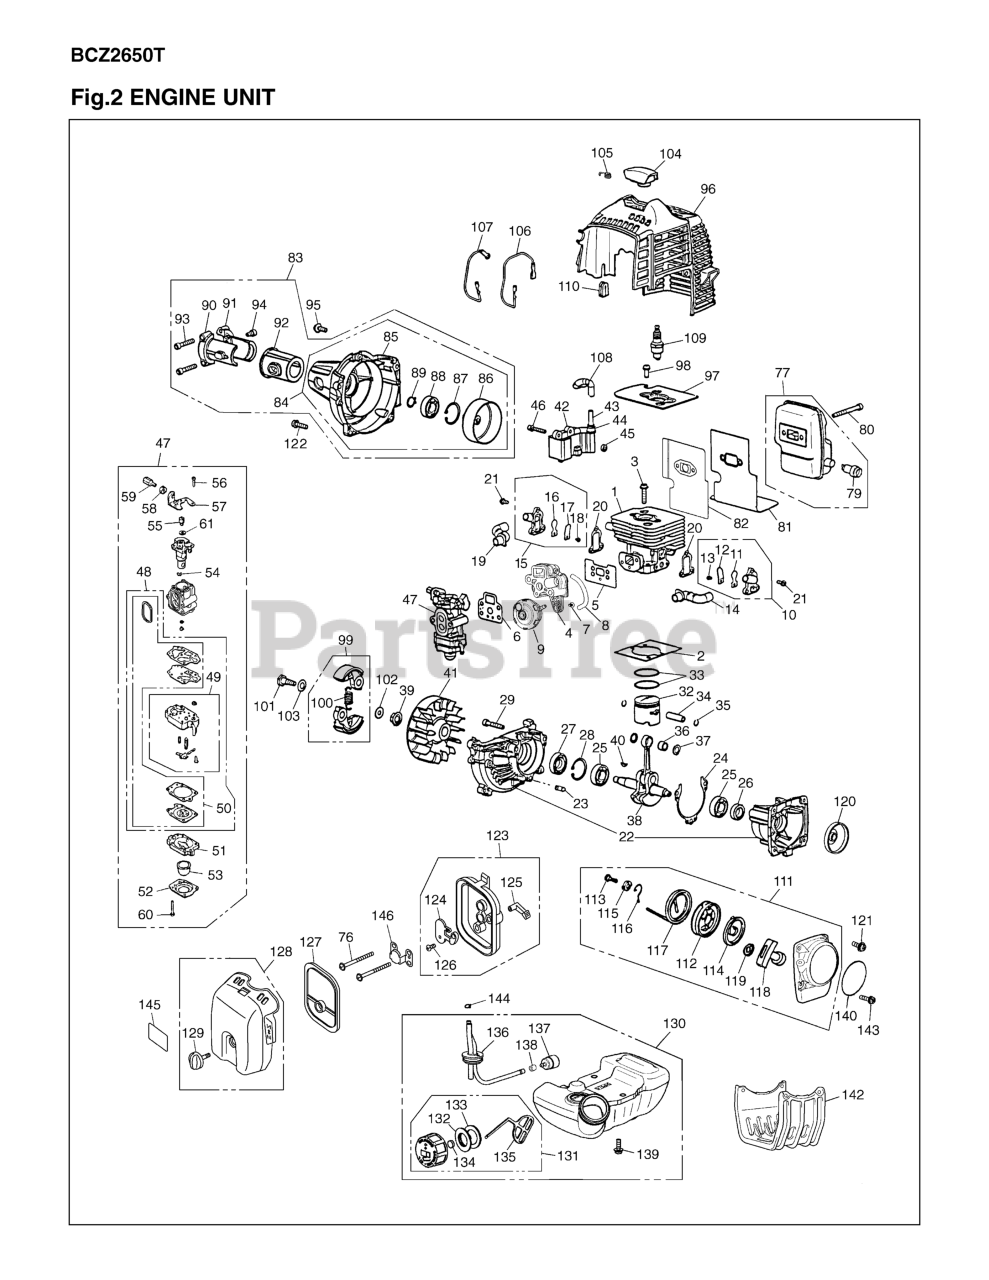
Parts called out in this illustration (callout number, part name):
1	CYLINDER
2	GASKET, BASE
3	STOPPER (TOOL)
4	INSULATOR
5	GASKET, INSULATO
6	GASKET, CARB (RP
9	PUMP ASSY
10	REED VALE (S) ASSY
11	REEDVALVE
12	STOPPER
13	SCREW, M3 x 8
14	PIPE AIR (S)
15	REEDVALVE (F) ASSY
16	REEDVALVE
17	STOPPER
18	SCREW, M3 x 8
19	PIPE AIR (F)
20	GASKET, VALVE
21	SCREW
22	CRANKCASE-C (RPL
23	PIN
24	GASKET
25	BEARING MAIN
26	SEAL
27	SEAL, OIL (RPLS
29	BOLT
33	RING, PISTON
34	PIN (RPLS T15134
35	RING, SNAP (RPLS
38	CRANKSHAFT COMP(
39	NUT (RPLS 1140-4
40	KEY
41	ROTOR
42	COIL-A
46	BOLT TORX
47	CARBURETOR ASSY
48	REBUILD KITxxx
49	BODY, PUMP
50	KIT, GASKET (RPL
51	BODY
52	COVER, PUMP
53	PUMP, PRIMING
54	RING
58	NUT
59	SCREW
60	SCREW
61	WASHER
79	ARRESTER
80	BOLT
82	PLATE, MUFFLER
83	COVER ASSY
84	COVER COMP. (R-3
85	COVER, FAN (RPLS
86	DRUM (RPLS 48103
88	BEARING
90	BRACKET (A) (RPL
91	BRACKET (B) (RPL
92	CUSHION
93	BOLT
94	BOLT M5X14
95	BOLT, TORX
96	COVER, ENGINE
98	BOLT
99	SHOE
100	SPRING
101	BOLT
102	WASHER
103	WASHER (RPLS 114
104	CAP(RPLS 4810721
105	SPRING(RP-500302
106	CORD (BLACK)
107	CORD, EARTH (RED
108	TUBE (RPLS 26307
109	SPKPLUG(CMR7H)(R
110	GROMMET
111	RECOIL ASSEMBLY
112	REEL
113	SCREW
114	SPRING, SPIRAL
115	COLLAR
116	ARM
117	ROPE (RPLS 45007
118	KNOB (RPLS 3330-
119	PLATE, STOPPER
120	PULLEY
121	BOLT M5X14
122	BOLT
123	BODY - A
124	PLATE, CHOKE
126	SCREW
127	ELEMENT
128	CLEANER COVER AS
129	CLEANER KNOB
130	TANK ASSY
131	CAP ASSY
132	HOLDER (RPLS 450
133	PACKING
134	FILTER
135	STOPPER
136	PIPE COMPLETE
137	FUEL FILTER
138	CLIP (RPLS 28413
139	BOLT
140	LABEL, RECOIL
143	BOLT
144	CLIP
